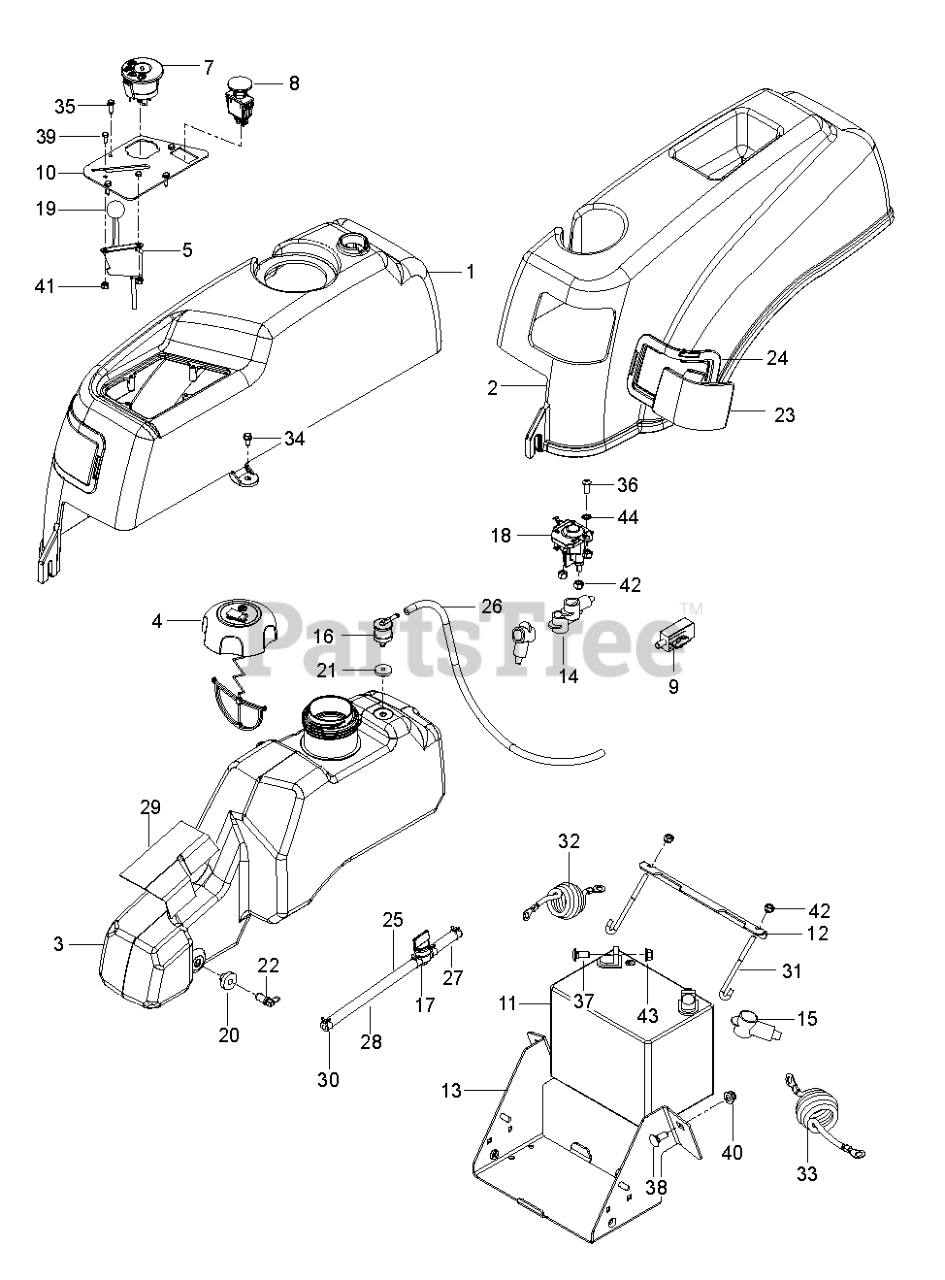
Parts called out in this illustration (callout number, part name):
1	FENDER.RT.BLK.3IN.FUEL.NECK
2	FENDER, LT, BLK
3	FUEL TANK ASSY LARGE 3 NECK TH
4	CAP ASSY FUEL 3" BLACK
5	CABLE.THROTTLE.20"
7	IGNITION SWITCH
8	RP SWITCH.PTO.TERMINAL.STD.RED
9	SWITCH.INTRLCK.CLUTCH.
10	PLATE.CONTROL.CONSOLE.BLACK
11	Battery 12 Volt 25 AMP
12	BRACKET.PNT.MOUNT.BATTERY.EDIP
13	BOX.PNT.BATTERY.RZ.EDIP
14	Terminal Cover (For Solenoid) (AYP part number)
15	INSULATOR
16	VALVE.FUEL.CHECK
17	FUEL VALVE
18	SOLENOID.STARTER.BRASS.PLUNGER
19	KNOB ROUND BALL
20	Bushing (Dana part number) (AYP part number)
21	GROMMET.ROV.SENTEC
22	Stem, Tank Fuel (AYP part number)
23	PANEL, LT
24	RING, LT BLK
25	FUEL.HOSE.SHUT.OFF.ASM.10".3"
26	HOSE.3/16".VAPOR.LINE.18"LGTH
27	HOSE.1/4".LOW.PERM.FUEL.LN.3"
28	HOSE.1/4".LOW.PERM.FUEL.LN.10"
29	SHIELD, HEAT
30	Clamp Hose Black (AYP part number)
31	HOOK.J.BATTERY
32	CABLE BATTERY GROUND RZ
33	CABLE BATTERY POS RZ
34	SCREW
35	SCR #10-12X3/4 HEX WAS HD ZD
36	SCR 1/4-20 X 5/8 BTN SKT HD ZD
37	BOLT 5/16C X 3/4" CARRIAGE
38	RHSNB 3/8C X 1
39	HCS #10-24 X 1/2
40	NUT 3/8-16 HEX FLG NYLOC ZD
41	NUT 10-24 NYLOC
42	NUT 1/4-20 NYLOC
43	5/16-18 NYLOC FLANGE NUT
44	WASHER 1/4 INT TOOTH
